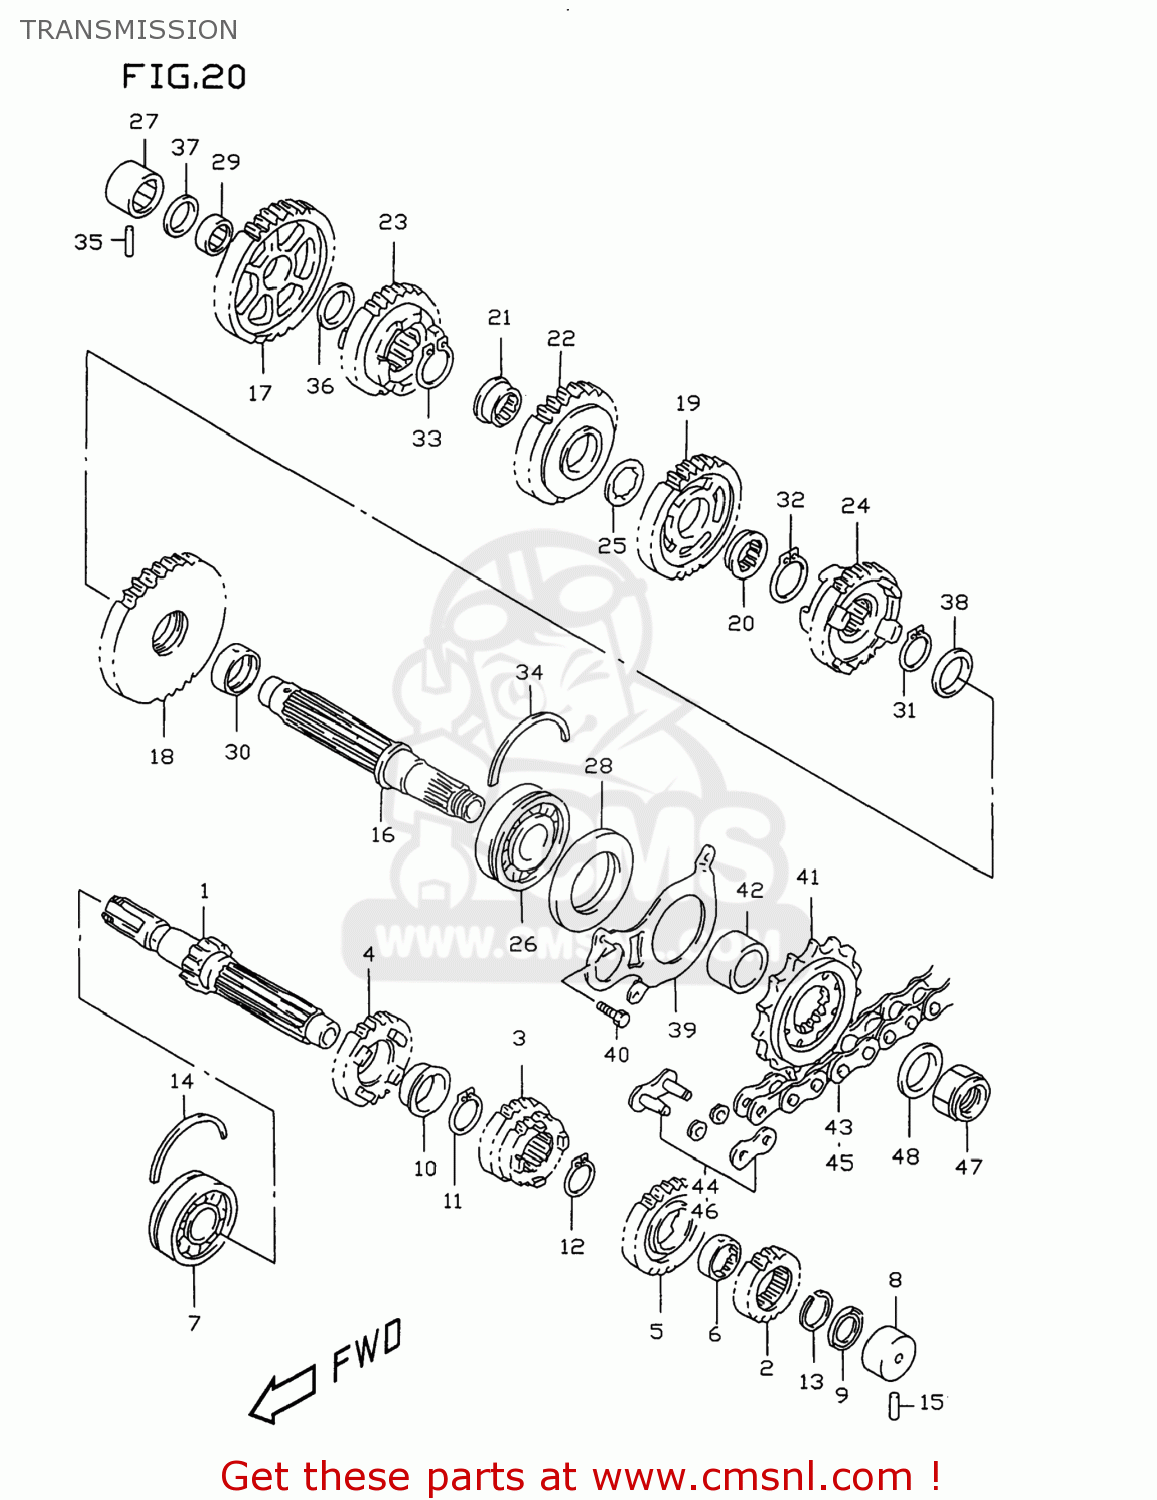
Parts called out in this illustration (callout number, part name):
1	SHAFT,COUNTER
2	GEAR,SECOND DRIVE
3	GEAR,3RD & 4TH DRIVE
4	GEAR,5TH DRIVE
5	GEAR,6TH DRIVE
6	BUSH,6TH DRIVE GEAR
7	BEARING(25X62X17)
8	BEARING
9	SEAL,OIL(20X31.2X2.7)
10	BUSH(28X32X2)
11	CIRCLIP
12	CIRCLIP
13	CIRCLIP
14	C RING
15	PIN
16	SHAFT,DRIVE
17	GEAR,1ST DRIVEN
18	GEAR,2ND DRIVEN
19	GEAR,THIRD DRIVEN
20	BUSH
21	BUSH
22	GEAR,FOURTH DRIVEN
23	GEAR,FIFTH DRIVEN
24	GEAR,6TH DRIVEN(NT:28)
25	WASHER,LOCK
26	BEARING(28X70X18)
27	BEARING(20X34X20)
28	SEAL,OIL(34.8X70X6)
29	BUSH(22X26X9)
30	BUSH(28X32X9.5)
31	CIRCLIP
32	CIRCLIP
33	CIRCLIP
34	C RING
35	PIN
36	WASHER
37	WASHER
38	SHIM(28X38X1)
39	RETAINER,DRIVE SHAFT OIL SEAL
40	BOLT
41	SPROCKET,ENGINE(16T)
42	SPACER,ENG SPROCKET
43	CHAIN ASSEMBLY RK50MFOZ1.1
44	JOINT SET,DRIVE CHAIN
45	CHAIN ASSEMBLY RK525R0Z2.1
46	JOINT SET,DRIVE CHAIN
47	NUT
48	WASHER,THRUST
